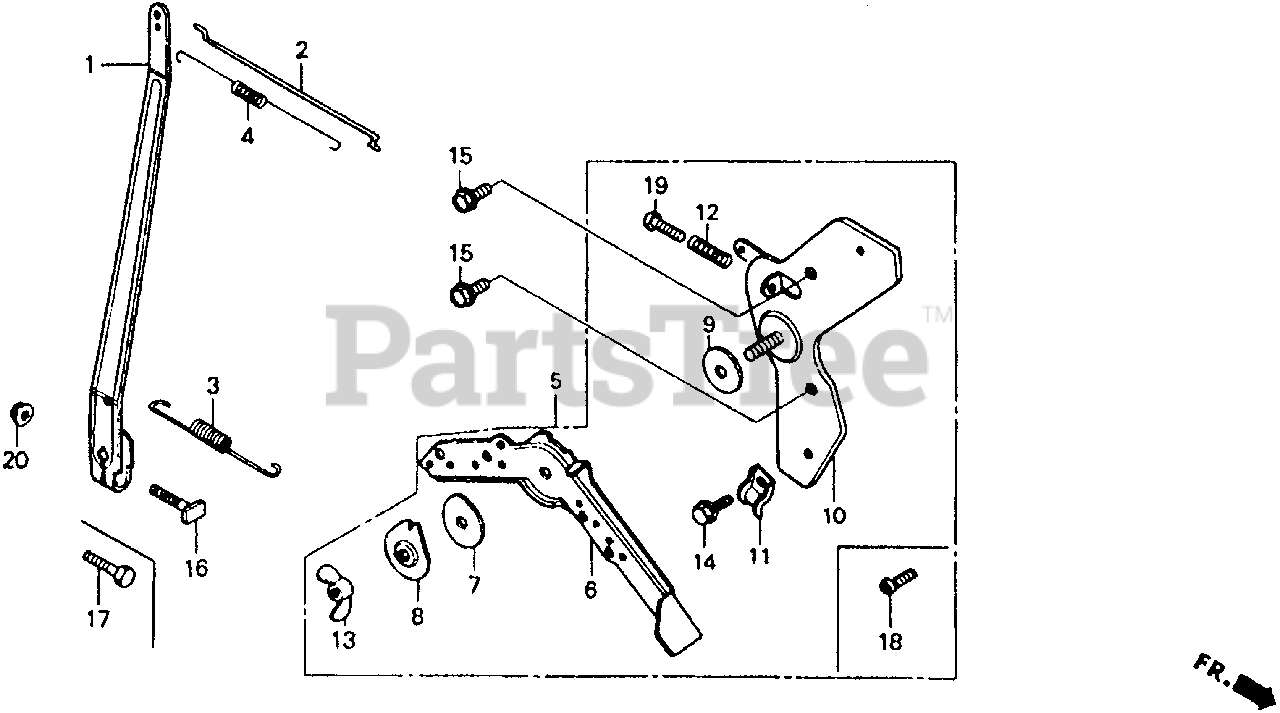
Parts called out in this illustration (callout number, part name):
1	ARM, GOVERNOR
2	ROD, GOVERNOR
3	SPRING, GOVERNOR
4	SPRING, THROTTLE RETURN
5	CONTROL ASSY.
6	LEVER, CONTROL
7	SPRING, LEVER
8	WASHER, CONTROL LEVER
9	SPACER, CONTROL LEVER
10	BASE, CONTROL LEVER
11	HOLDER, CONTROL CABLE
12	SPRING, CONTROL ADJUSTING
13	WINGNUT (6MM)
14	BOLT, FLANGE (5X10)
15	BOLT, FLANGE (6X12) (CT200)
16	BOLT, GOVERNOR ARM
17	BOLT, HEX. (6X20)
18	SCREW, PAN (5X10)
19	SCREW, PAN (5X22)
20	NUT, FLANGE (6MM)
